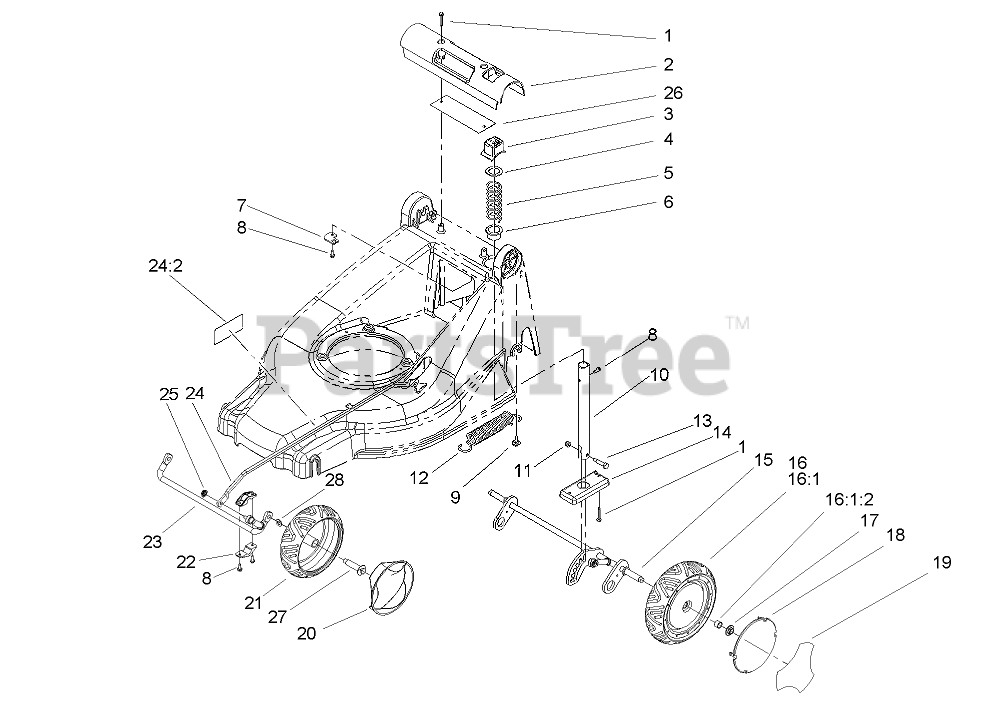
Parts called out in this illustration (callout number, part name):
1	SCREW-HWH
2	HANDLE-DECK
3	BUTTON-HOC
4	WASHER-BACKUP
5	SPRING-COMPRESSION, HOC
6	BUSHING-HOC
7	BRACKET-CABLE, TRACTION
8	SCREW-TAPTITE
9	SCREW-SHOULDER
10	PIPE-HOC
11	NUT-LOCK, NI
12	SPRING-EXTENSION, HOC
13	BOLT-SHOULDER
14	PLATE-SUPPORT, HOC
15	REAR AXLE ASM
16	WHEEL AND TIRE ASM
16:1	Wheel ASM
16:1:2	BUSHING
17	NUT-LOCK, FLANGED
18	COVER-WHEEL, SMART
19	DECAL-SMART WHEEL
20	COVER-WHEEL
21	WHEEL ASM
22	MOUNT-AXLE, FRONT
23	FRONT AXLE ASM
24	ROD ASM
24:2	DECAL-HOC
25	PALNUT
26	COVER-HANDLE
27	BOLT-SHOULDER
28	WASHER
